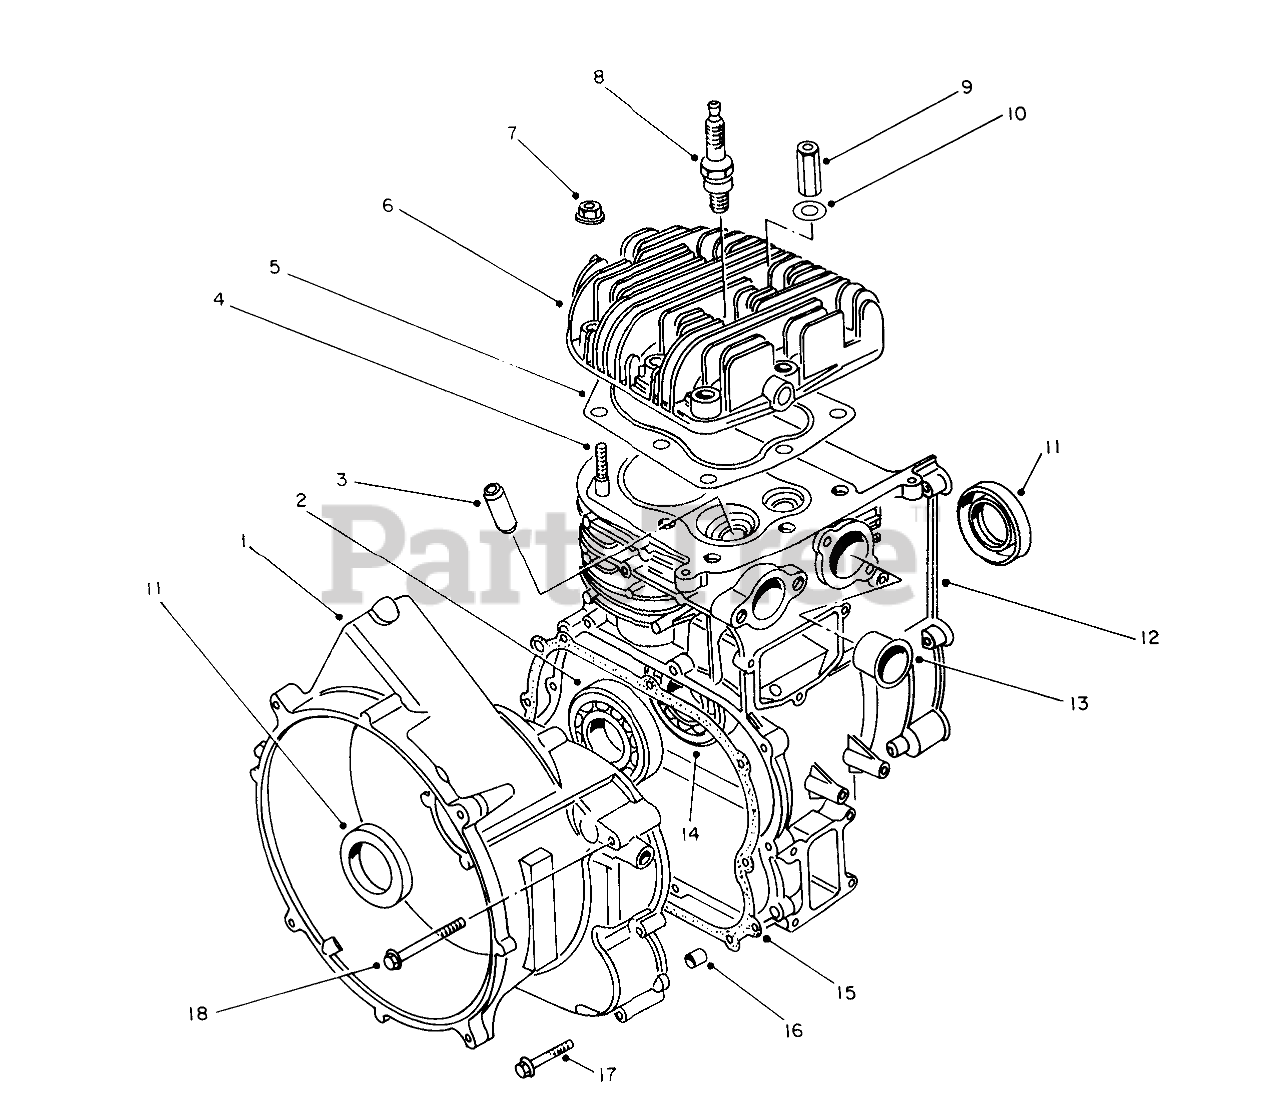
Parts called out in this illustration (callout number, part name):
1	Cover Assembly
2	Screw
3	VALVE GUIDE
4	Stud Bolt
5	CYL HEAD GASKET
6	Cylinder Head
8	SPARK PLUG
10	Washer
11	OIL SEAL
12	Cylinder Assembly
13	Exhaust Guide
14	Screw
15	Gasket
